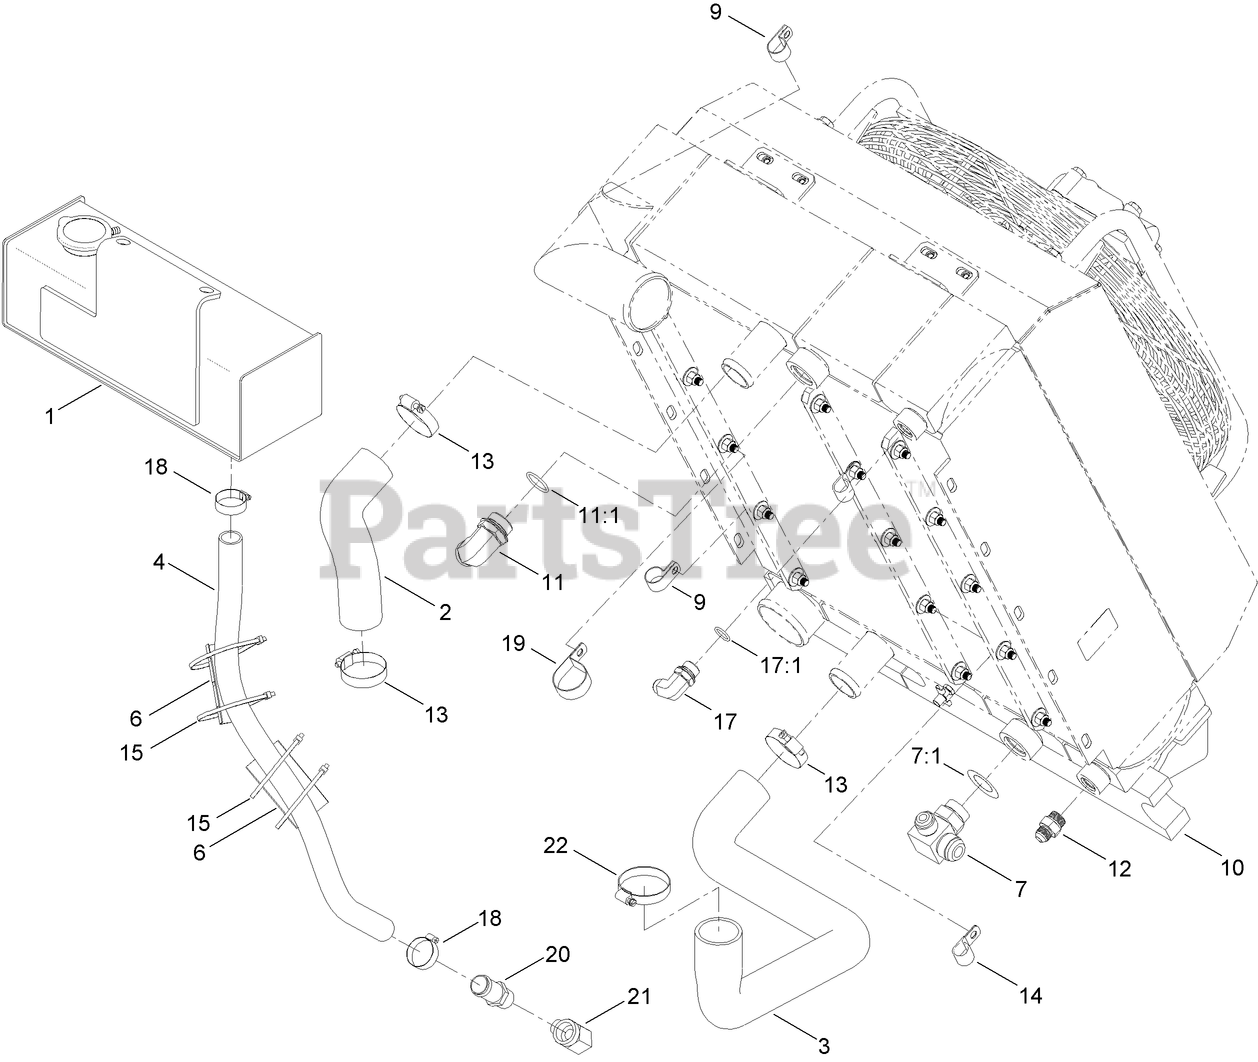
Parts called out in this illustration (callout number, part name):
1	COOLANT RECOVERY TANK ASM
2	HOSE-RADIATOR, TOP
3	HOSE-RADIATOR, BOTTOM
4	HOSE-INLET
6	PROTECTOR-HOSE
7	FITTING-HYD, SPECIAL
7:1	O-RING
9	CLAMP-R
10	SEAL-FOAM
11	ELBOW-90 DEG
11:1	O-RING
12	FITTING-STRAIGHT
13	CLAMP-HOSE
14	CLAMP-R
15	TIE-CABLE
17	FITTING-90 DEG
17:1	O-RING
18	CLAMP-HOSE
19	CLAMP-R
20	FITTING-STRAIGHT
21	FITTING-ELBOW, 90 DEG
22	CLAMP-HOSE
